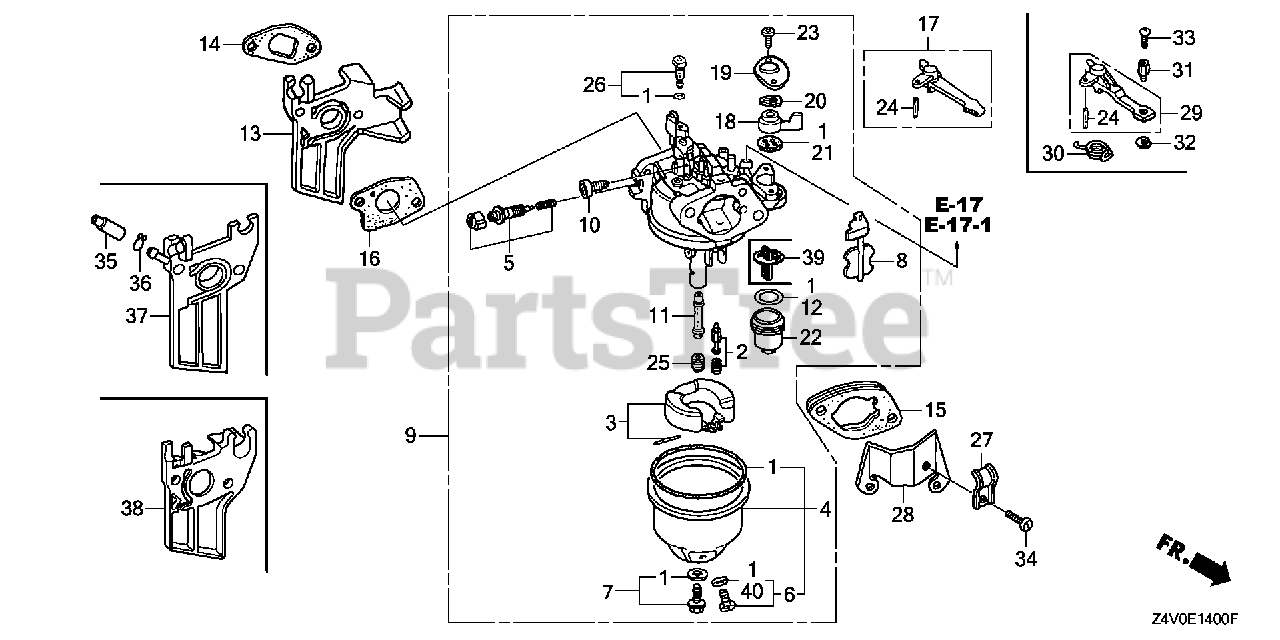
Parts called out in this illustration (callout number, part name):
1	GASKET SET
2	VALVE SET, FLOAT (SEAT NOT INCLUDED)
4	CHAMBER SET, FLOAT
5	SCREW SET, PILOT
6	SCREW SET, DRAIN
7	SCREW SET
9	CARBURETOR ASSY. (BE64Y A)
10	SCREW, THROTTLE STOP
11	NOZZLE, MAIN
12	GASKET, FUEL STRAINER CUP
13	INSULATOR, CARBURETOR
14	GASKET, INSULATOR
15	SPACER, CARBURETOR
16	GASKET, CARBURETOR
17	LEVER, CHOKE (STD)
18	LEVER, PETCOCK
19	PLATE, LEVER SETTING
20	SPRING, PETCOCK LEVER
21	GASKET, PETCOCK
22	CUP, FUEL STRAINER
23	SCREW, PAN (3X6)
24	PIN, SPRING (2X12)
25	JET, MAIN (#72)
25	JET, MAIN (#68)
25	JET, MAIN (#70)
26	JET SET, PILOT (#45)
40	WASHER, PLAIN (6.2X10.7 DRAIN)
